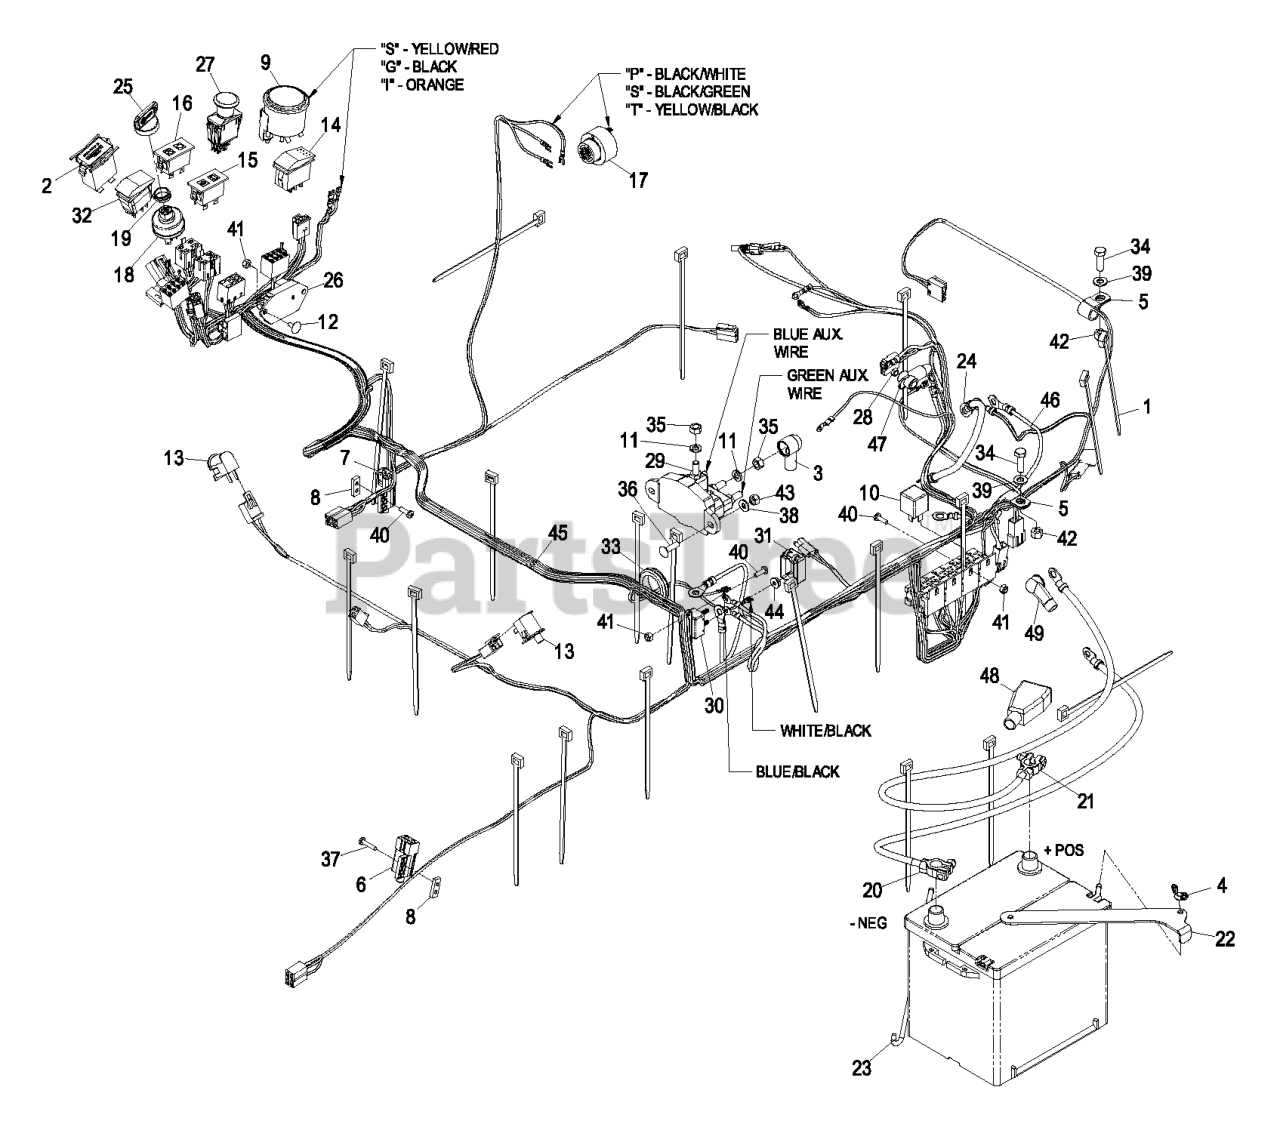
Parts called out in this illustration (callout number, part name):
1	TIE-PLASTIC
2	METER-HOUR
3	INSULATOR-SOLENOID
4	WINGNUT
5	CLIP-LOOM
6	SWITCH-BRAKE
8	PLATE-TAPPED
9	GAUGE-TEMPERATURE
11	WASHER-LOCK
12	BOLT-CARR
13	SWITCH-BAIL
15	LAMP-WARNING
16	LAMP-WARNING
17	ALARM-TONE, DUAL
19	NUT-SWITCH, IGNITION
20	CABLE-BATTERY NEGATIVE
21	CABLE-BATTERY POSITIVE
22	STRAP, BATTERY
23	BOLT-HOLDDOWN
24	CABLE-ENGINE NEGATIVE
25	KEY-IGNITION
26	MODULE-DELAY, SEAT
27	SWITCH-PTO
28	NUT-HEX
29	CONTACTOR, REVERSING POLA
30	CIRCUIT BREAKER,40A
31	COVER,CIRCUIT BREAKER
32	SWITCH-ROCKER
33	GROMMET-RUBBER
34	SCREW-HH
35	NUT-HEX
36	SCREW-CARR
37	SCREW-PPH
38	WASHER-FLAT
39	WASHER-PLAIN
40	SCREW-PPH
41	NUT-LOCK, NI
42	NUT-LOCK, NI
43	NUT-LOCK, NI
44	NUT-KEPS
45	HARNESS,WIRING FMZ KD902
46	HARNESS,AUX HYDRAULICS
47	CAP-INSULATOR, RED
48	INSULATOR-TERMINAL, BATTE
49	INSULATOR-STARTER
